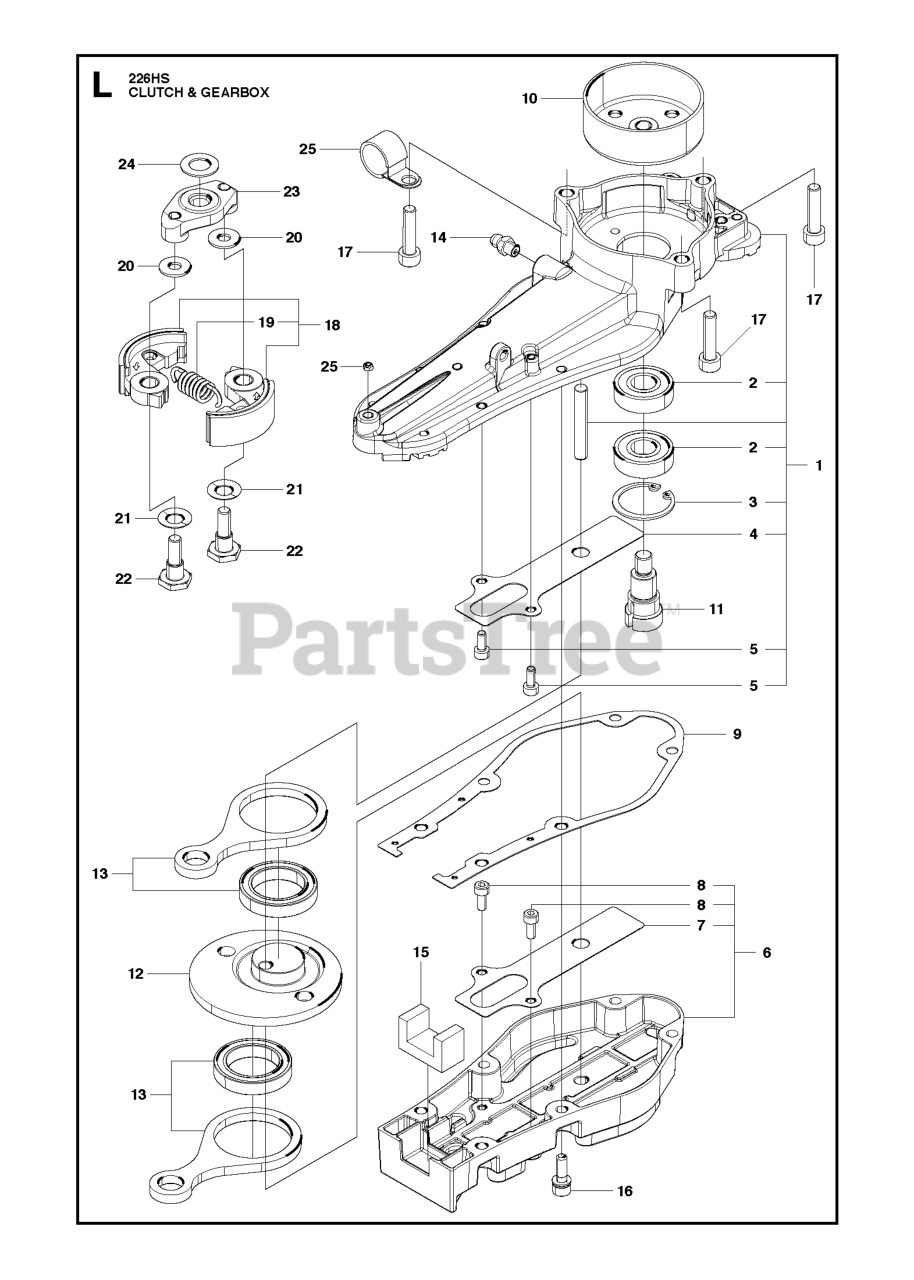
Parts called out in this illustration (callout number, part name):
1	GEAR CASE COMPLETE
6	GEAR CASE BOTTOM COMP
11	GEAR DRIVE
12	GEAR DRIVE
13	ROD ASSY
13	ROD COMP
23	PLATE CLUTCH
